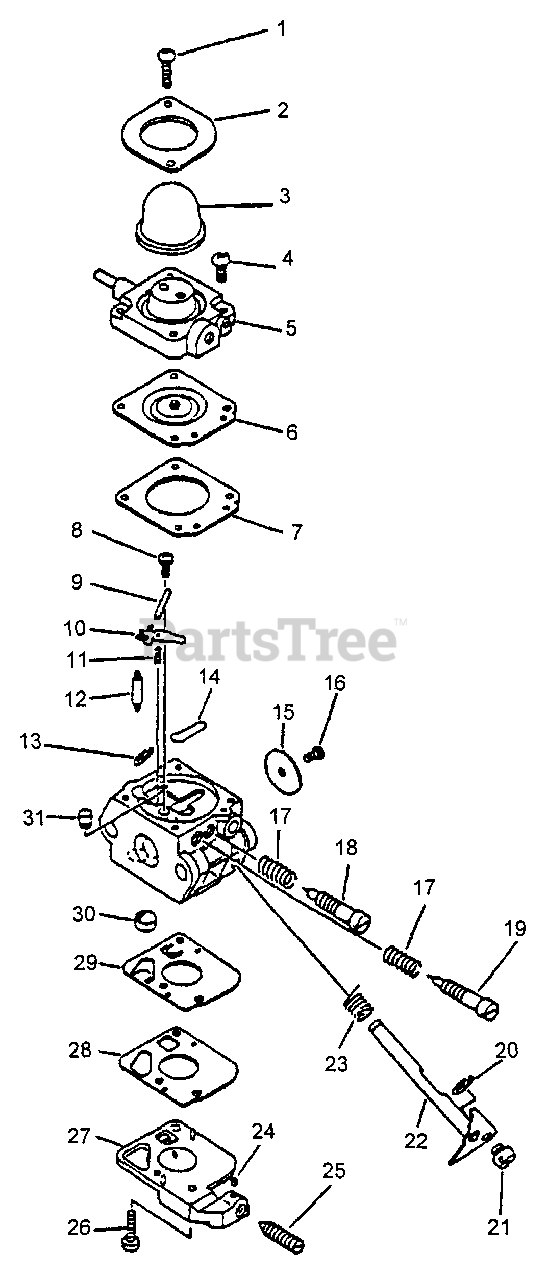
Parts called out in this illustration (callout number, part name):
1	SCREW, PURGE BASE
2	RETAINER, PURGE BULB
3	BULB, PURGE
4	SCREW, RETAINER
5	BASE, PURGE
6	DIAPHRAGM, METERING
7	GASKET, METERING
8	SCREW
9	PIN
10	LEVER, METERING
11	SPRING, METERING LEVER
12	VALVE, NEEDLE
13	RING, RETAINING
14	PLUG, WELCH
15	VALVE, THROTTLE
18	NEEDLE - MIXTURE
19	NEEDLE - HIGH SPEED
20	RING, RETAINING
22	SHAFT, THROTTLE
23	SPRING, RETURN
24	PIECE, FRICTION
25	SCREW, IDLE ADJUST
26	SCREW, PUMP COVER
27	BASE, PURGE
28	GASKET, PURGE
29	DIAPHRAGM, PURGE
30	STRAINER
31	NOZZLE, CHECK VALVE
